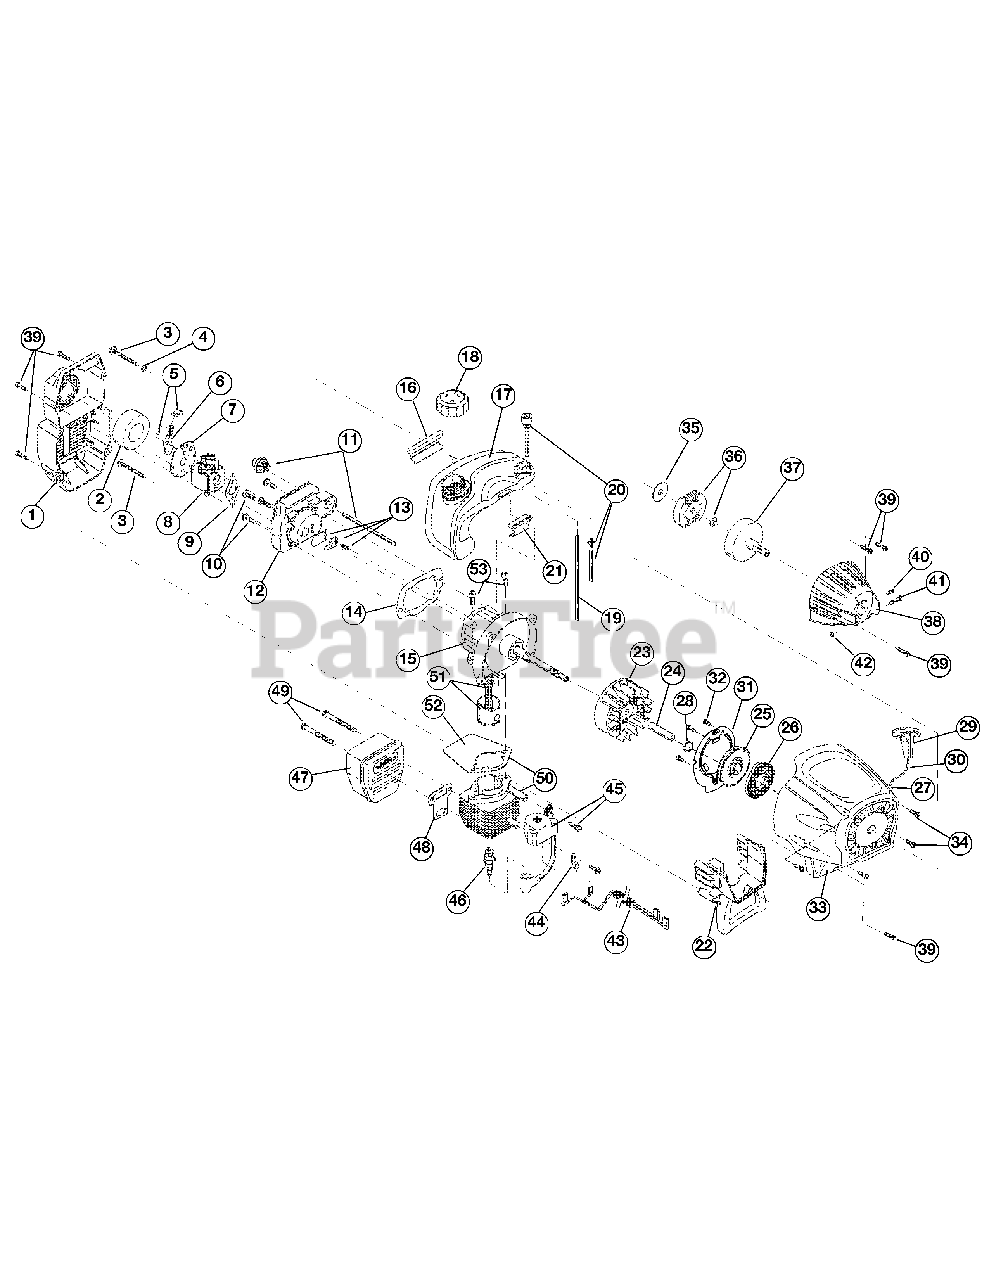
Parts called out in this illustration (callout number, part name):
1	Air Cleaner Cover Assembly (includes 2 & 39)
2	Air Cleaner Filter
3	Carburetor Mounting Screw Assembly
4	Wavey Washer
5	Choke Knob w/Screw
6	Choke Lever (includes 5)
7	Choke Plate (includes 6)
8	Carburetor Assembly (includes 9 & 20)
9	Carburetor Gasket
10	Carb Mount Screw
11	Primer & Hose Assembly
12	Carb Mount Assembly (includes 10, 13 & 14)
13	Reed Assembly
14	Carburetor Mount Gasket
15	Crankcase Service Assembly (includes 10)
16	Rear Mounting Pad
17	Fuel Tank Assembly (includes 18-20)
18	Fuel Cap Assembly
19	Fuel Return Line
20	Fuel Line Assembly
21	Front Mounting Pad
22	Shroud Extension & Stand (includes 39)
23	Flywheel Assembly
25	Recoil Pulley Assembly (includes 26, 28 & 30)
26	Recoil Spring
27	Rope Guide
28	Pulley Retainer
29	Pull Handle
31	Pressure Plate Assembly (includes 32)
32	Plate Screw
33	Starter Housing Assembly (includes 25-32, 34 & 39)
34	Housing Screw
35	Clutch Washer
36	Clutch Rotor Assembly
37	Clutch Drum Assembly
38	Clutch Cover Assembly (includes 39-42)
39	Cover Screw
40	Anti-Rotation Screw
41	Clamping Screw
42	Clamping Nut
43	Wire Leads and Sleeve
44	Ground Tab
45	Module Assembly
47	Muffler Assembly (includes 48, 49 & spark arrestor)
48	Exhaust Gasket
49	Muffler Mounting Bolts
50	Cylinder Assembly (includes 52 & 53)
51	Piston and Rod Assembly
52	Cylinder Gasket
53	Cylinder Bolt
